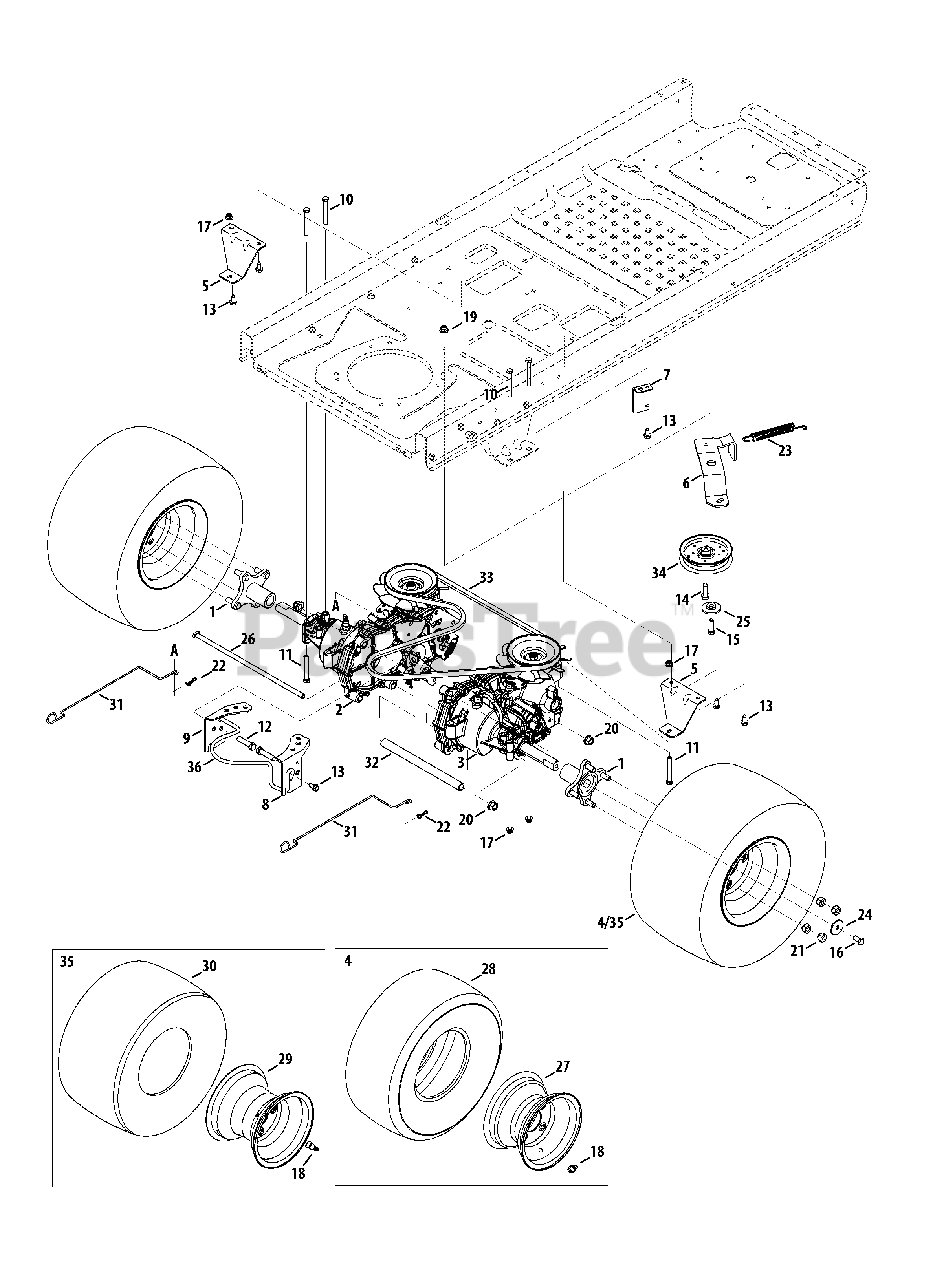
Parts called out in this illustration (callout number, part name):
1	Wheel Hub Assembly
2	Transmission Assembly, LH
3	Transmission Assembly, RH
4	Complete Wheel, 18 x 8.5-8 (42-Inch & 46)
5	Transmission Mounting Bracket
6	Idler Bracket
7	Spring Mounting Bracket
8	Transmission Bracket
9	Transmission Bracket
10	Hex Screw, 5/16-18 x 2.75
11	Hex Screw, 5/16-18 x 2.25
12	Hex Screw, 7/16-20 x 1.75
13	Hex Washer Screw, 5/16-18 x .750
14	Hex Washer Screw, 3/8-16 x 1.250
15	Hex Screw, 3/8-16 x 1.00
16	Hex Screw, 3/8-16 x .75
17	Flange Lock Nut, 5/16-18
18	Valve Tubeless
19	Flange Lock Nut, 3/8-16
20	Flange Lock Nut, 7/16-20
21	Lug Nut, 7/16-14
22	Bow-Tie Cotter Pin
23	Extension Spring, .75 Dia. x 6.02
24	Flat Washer, .390 x 1.50 x .134
25	Shoulder Spacer, .884 x .190
26	Rod, .405 Dia. x 14.0 LG
28	Tire Only, 18 x 8.5-8
29	Rim Only, (50-Inch & 54-Inch)
30	Tire Only, 18 x 9.5-8 (50-Inch & 54-Inch)
31	Bypass Rod
32	Tube, .51 ID x .75 OD x 10.2
33	Belt, A-Type x 67.0
34	Idler Pulley, 4.25 Dia.
35	Complete Wheel, 18 x 9.5-8 (50-Inch & 54-Inch)
36	Engine Keeper Rod (42-Inch)
